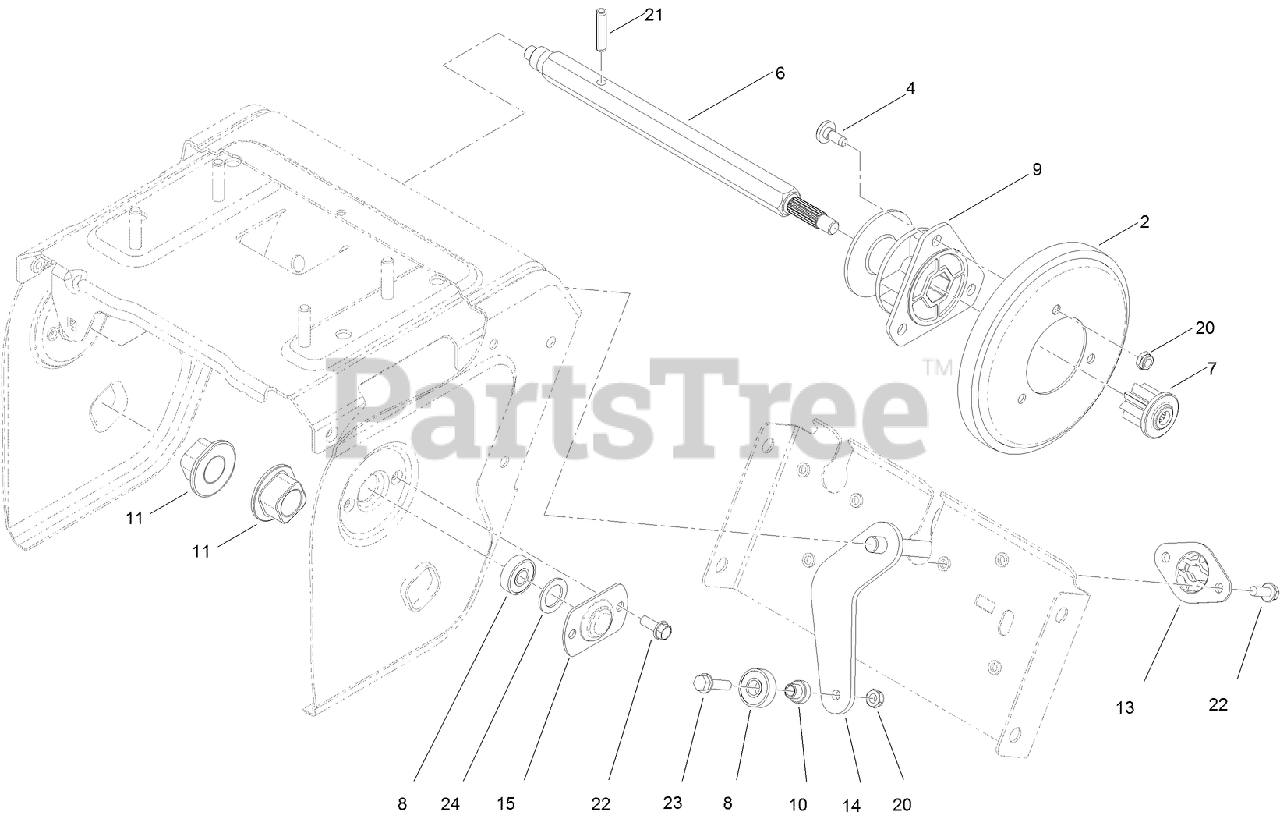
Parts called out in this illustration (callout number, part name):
2	WHEEL-FRICTION
4	SCREW-SHOULDER
6	SHAFT-HEX
7	GEAR-PINION, 8 TOOTH
8	BEARING-BALL
9	TRUNNION
10	SPACER-PLATE, SHIFT
11	BUSHING-AXLE
13	RETAINER-PLATE, SHIFT
14	SHIFT PLATE ASM
20	NUT-LOCK, NI
21	PIN-ROLL, SLOTTED
22	SCREW-HWH
23	SCREW-HWHTF
24	WASHER-RUBBER
